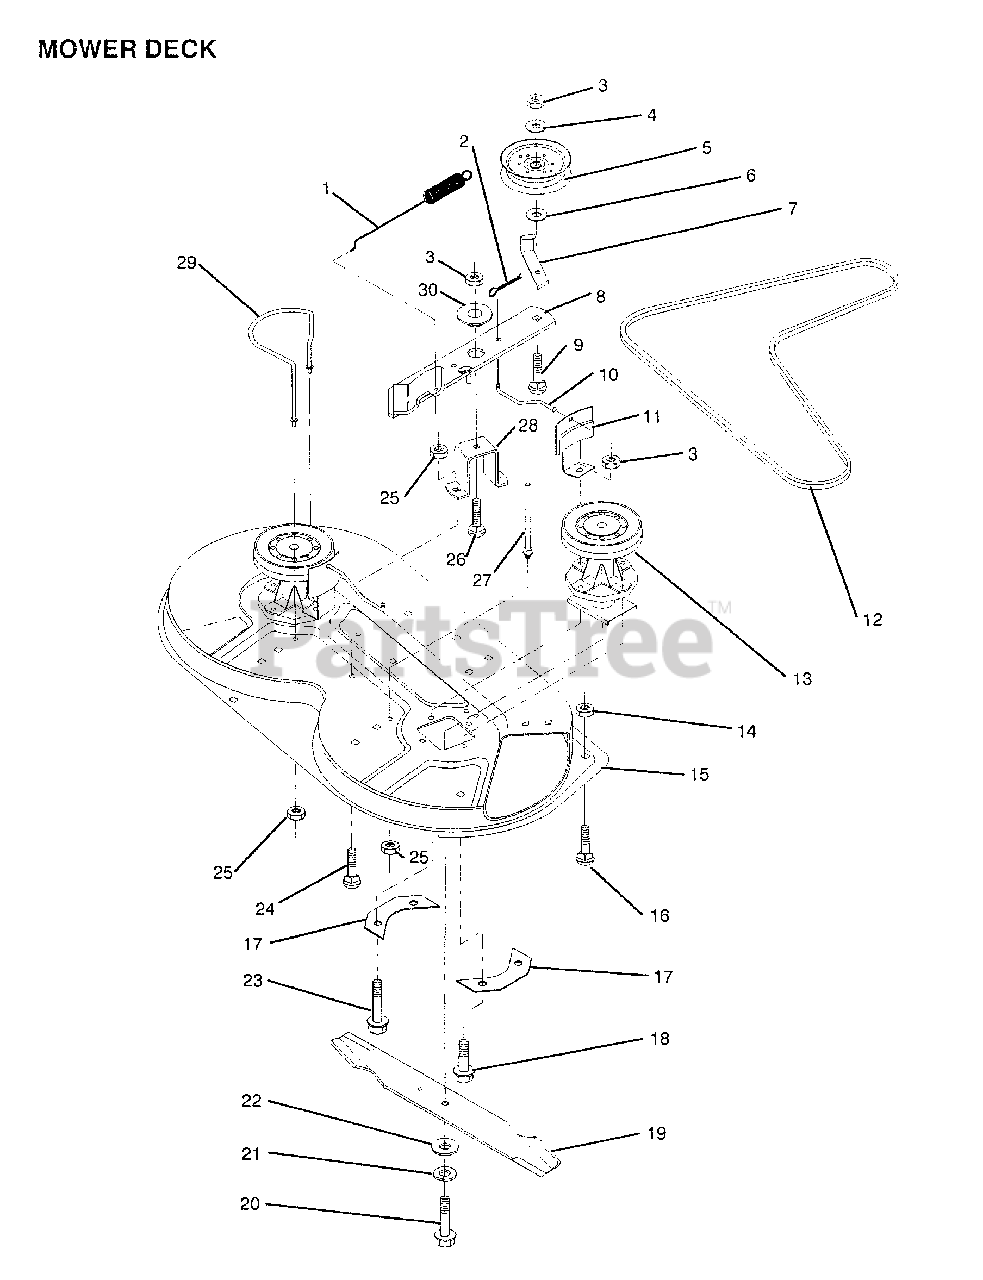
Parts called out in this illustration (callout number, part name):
4	WASHER
5	PULLEY IDLER
6	WASHER GT
8	IDLER ARM ASS'Y
9	BOLT CARRIAGE
10	ROD BRAKE
11	BRAKE LT
12	BELT.MOWER.79.75
13	MANDREL ASS'Y
16	BOLT
17	SUPPORT PLATE LT
18	SCREW
19	"BLADE.36""HIGH LIF"
20	BOLT.3/8-24X1-1/2
22	WASHER
23	SCREW
24	BOLT
26	BOLT D
27	"GUIDE,REAR BEL RH"
28	"SUPT,IDLER ARM"
29	GUIDE BELT LH
30	SPACER RETAINER
